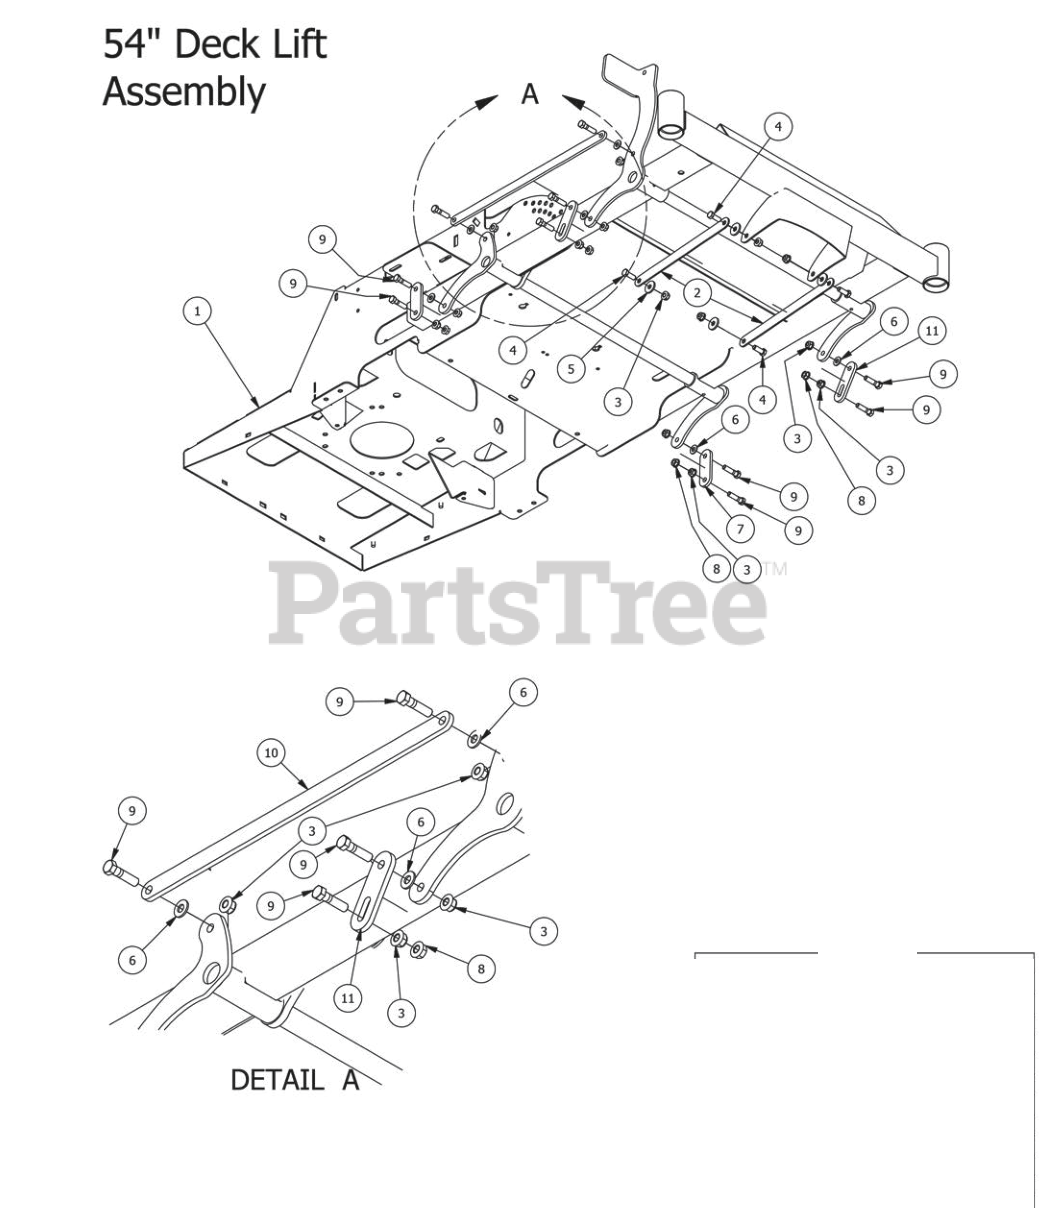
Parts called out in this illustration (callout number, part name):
1	2014 54" MZ Magnum Frame
2	MZ Front Arms
3	3/8" Nylock Flange Nut
4	3/8" x 1" Hex Bolt
5	.390 ID Plastic Washer
6	.360 ID Plastic Washer
7	48 Deck Spacer MZ
8	3/8" Flange Nut
9	3/8" x 1 1/2" Hex Bolt
10	Deck Linkage Rod
11	48 Deck Spacer MZ (Front)
